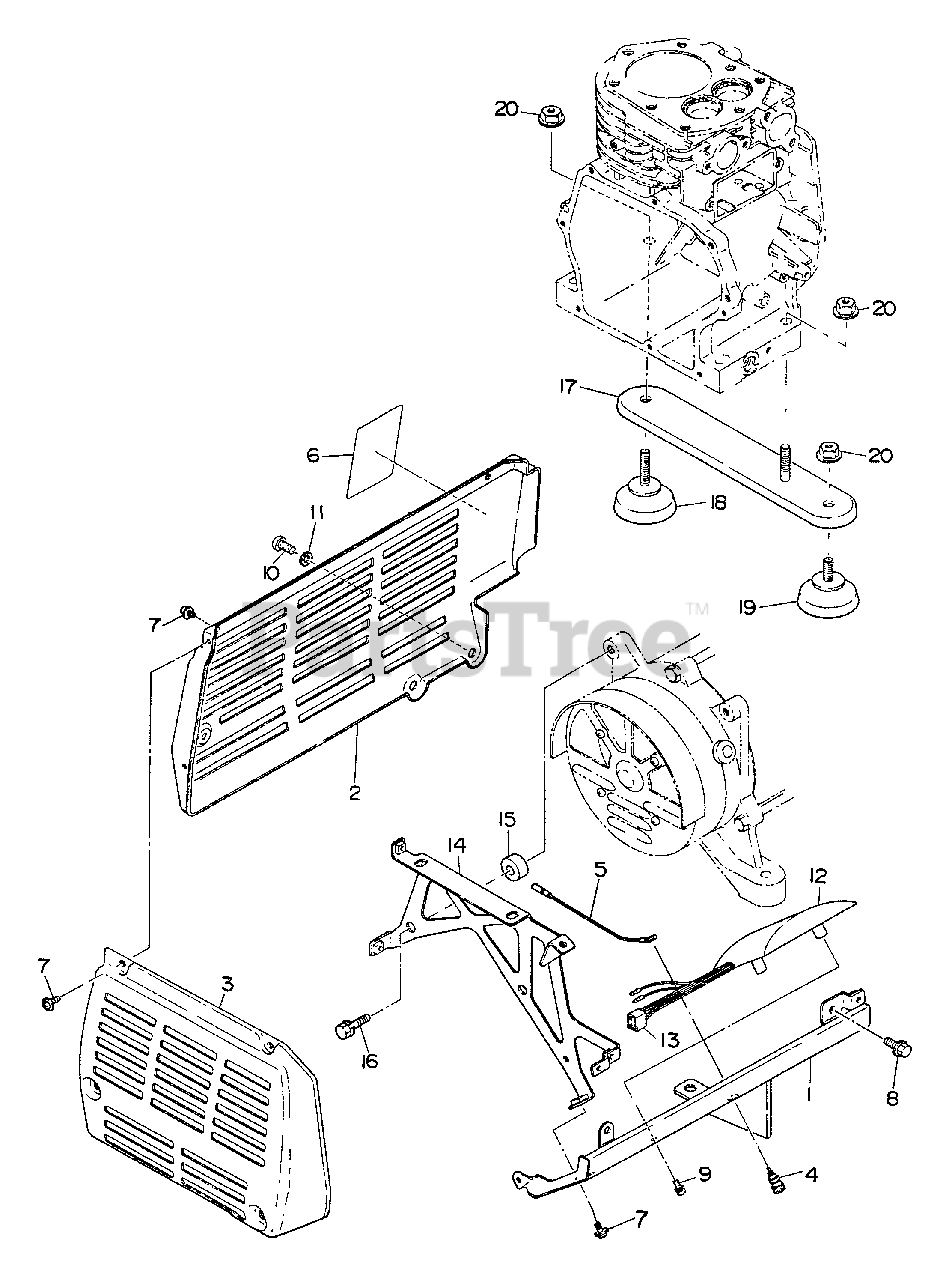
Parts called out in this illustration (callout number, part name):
1	FRONT COVER ASSY
2	REAR COVER, COMPL.
3	SIDE COVER
4	BOLT, TERMINAL - BLACK
5	LEAD - GROUND
6	LABEL - SPECIFICATION
7	SCREW
8	SCREW
9	SCREW
10	SCREW - PAN HEAD
11	WASHER
12	AVR, COMPL.
13	CONNECTOR (4P)
14	MOUNT ASSY
15	SPACER
16	BOLT
17	MOUNT ASSY
18	MOUNT ASSY
19	MOUNT ASSY
20	NUT, FLANGE
